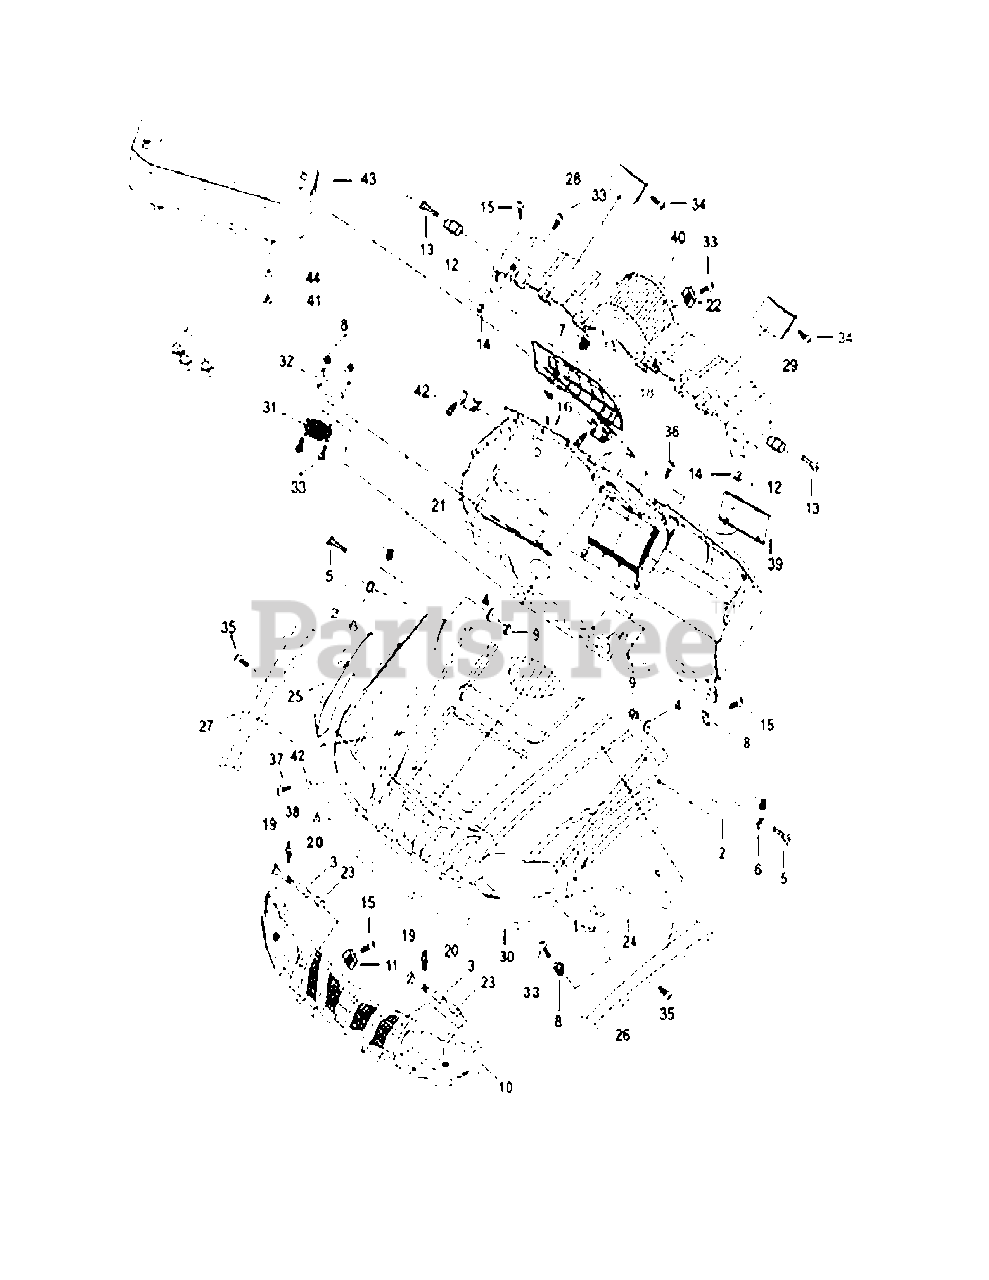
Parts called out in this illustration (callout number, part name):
1	HOOD - YELLOW
1	HOOD - CAMO
2	Front Cover Latch I
3	Bushing 25×13×30
4	Washer6×18×1.6
5	Hexagon Flange Bolt M6×30
6	Bushing 6.5×9×22×17
7	Glove Compartment Locker
8	Hexagon Flange Nut M6
9	Cap Nut M6×12
10	Headlight Cover
11	Screw Thread Clip M6×2
12	Latch Fixed Seat
13	Hexagon Flange Bolt M6×35
14	Hexagon Flange Self-Lock Nuts M6
15	Cross large plate head screw M6×16
16	Plastic Jaw
17	Cross Plate Head Tapping Screw ST3.9×13
18	Glove Compartment Cover
19	Shaft 12.5×89
20	Cotter pin 2×32
21	Dash Board
22	Screw Thread Clip M6×5
23	Bushing 25×13×13
24	Left Fender, Front Cover
25	Right Fender, Front Cover
26	Left Strip, Front Cover
27	Right Strip, Front Cover
28	Decoration Cover
29	Left Strip, Connecting Cover
30	Front Binding Strip, Front Cover
31	Speaker Cover
32	Speaker Box
33	Cross Large Plate Head Screw M6×20
34	Cross Plate Head Tapping ScrewST3.9×13
35	Cross Small Plate Head Tapping Screw ST4.2×13
36	Cross Countersunk Head Tapping Screw St6×20
38	Hexagon flange nut M5
39	CD Player Cover
40	CONNECTING COVER- YELLOW
40	CONNECTING COVER- CAMO
41	Hexagon Flange Nut M6
42	Cushion 5×15×1.2
43	Meter Assy(EFI Engine)
44	Washer6×18×1.6
